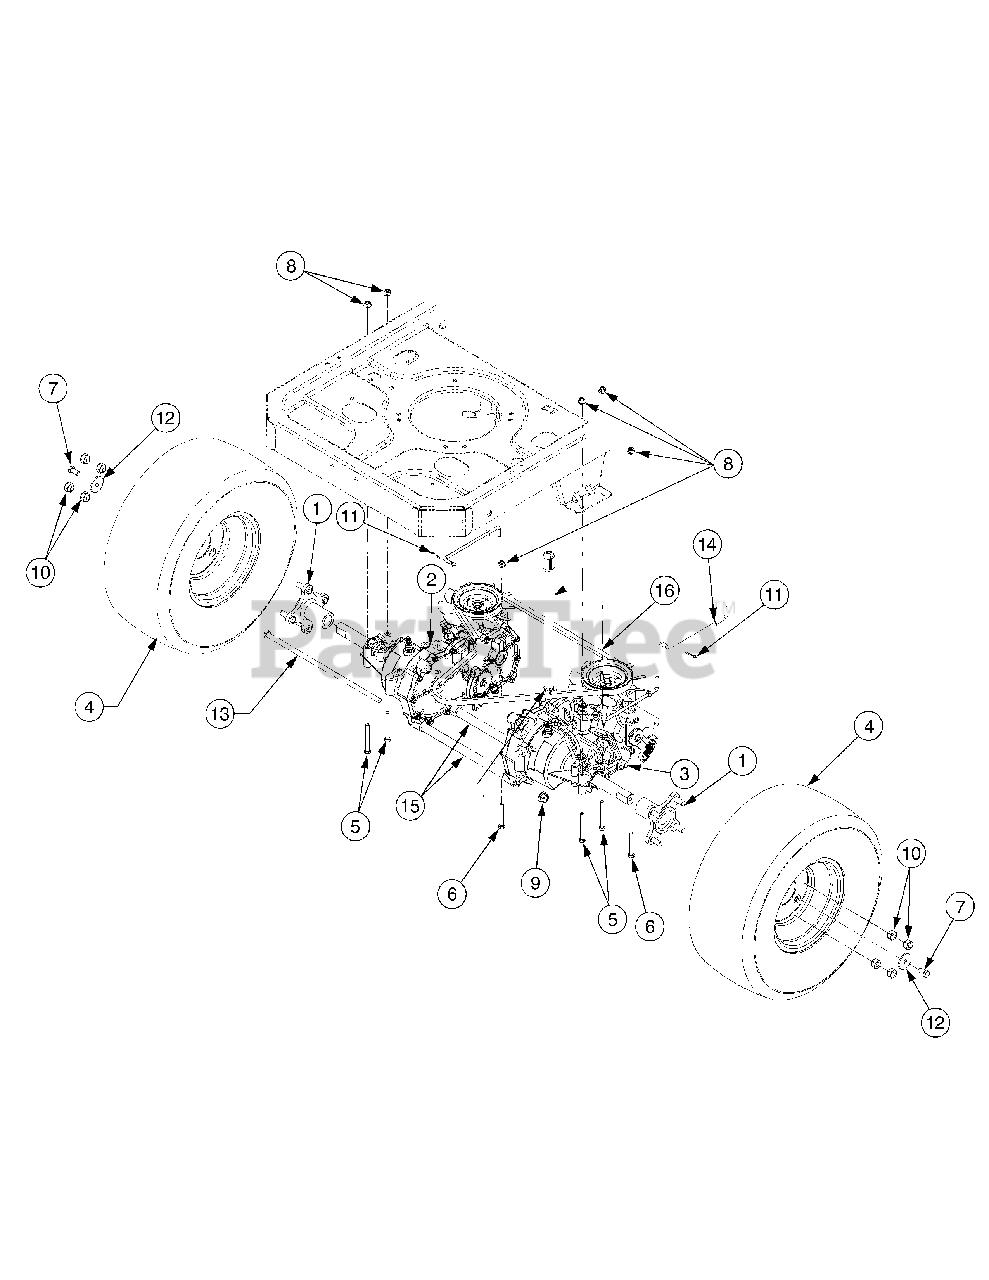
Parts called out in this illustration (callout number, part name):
2	Transmission Ass'y, LH
3	Transmission Ass'y, RH
4	Wheel Assembly - 42 Inch Model
4	Wheel Assembly - 50 Inch Model
5	Hex Scr 5/16-18 x 2.75
6	Hex Bolt 5/16-18 x 2.25
7	Hex Cap Lock Scr. 3/8-16 x .75 Gr.
8	Flange Locknut 5/16-18 Gr. F, Nylon
9	Flange Lock Nut, 7/16-20
10	Lub Nut, 7/16-14
11	Cotter Pin 3/32 x .75
12	Flat Washer .39 ID x 1.5 OD x .135
13	Rod, .405 x 14.0
15	Tube, .45 x .69 x 10.2
16	V-Belt, Type A Sec x 57.7
